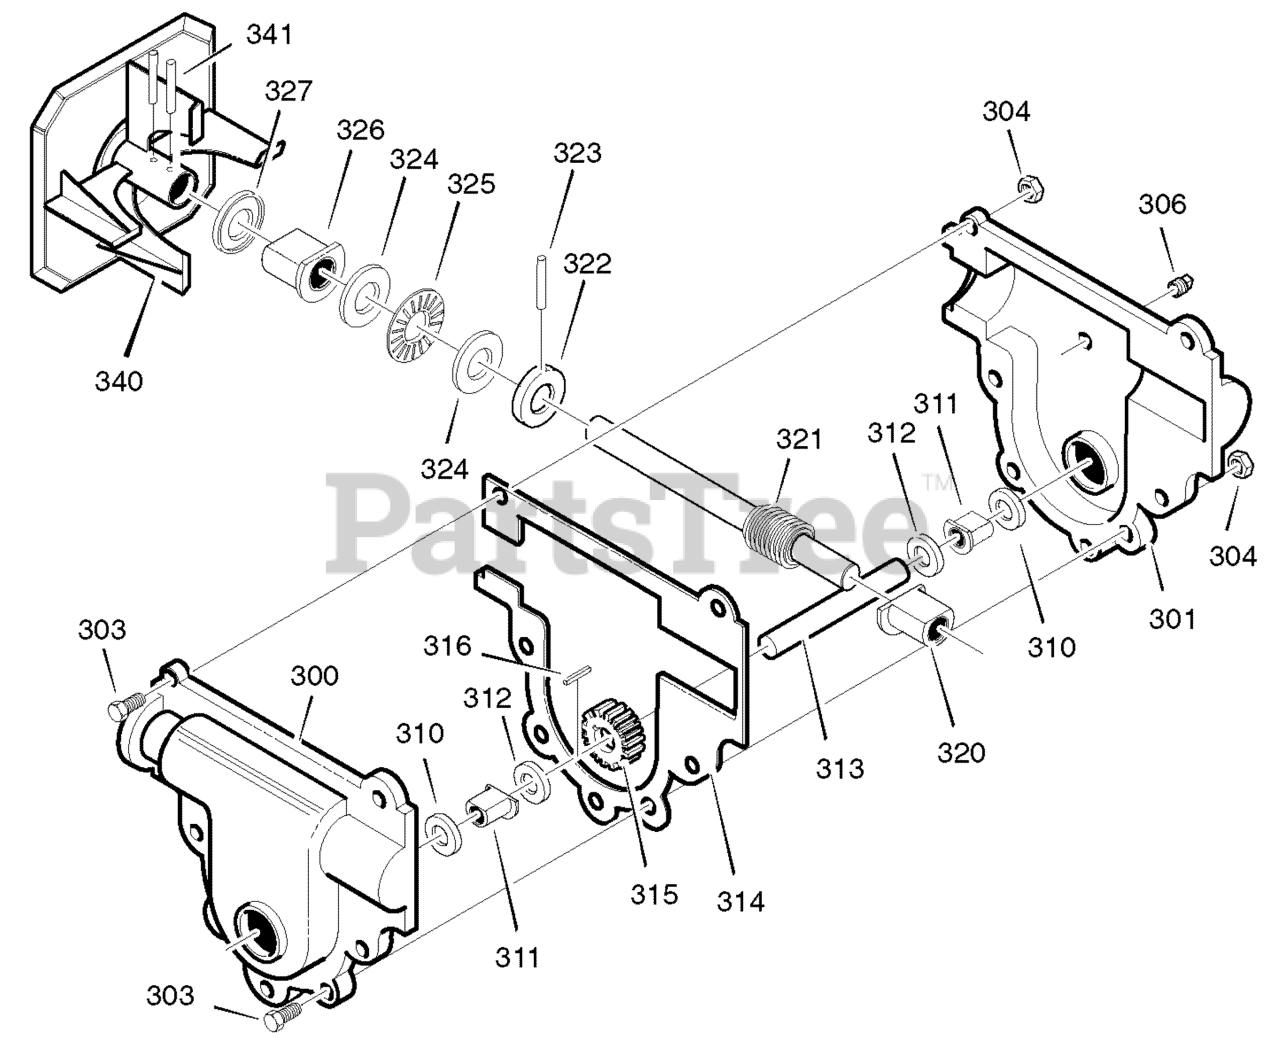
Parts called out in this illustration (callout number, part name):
300	CASE, GEAR, RH
301	CASE, GEAR, LH
303	SCREW,1/4-20X.75
304	NUT,1/4-20
306	SCREW, 3/8-16 x 0.50
310	SEAL, OIL
311	BEARING, FL
312	WASHER, FLAT
313	SHAFT, AUGER OUTPUT
314	GASKET, GEAR BOX
315	GEAR, WORM
316	KEY, WOODRUFF #61
320	BRNG, FL
321	SHAFT, AUGER INPUT (IMPELLER)
322	COLLAR, THRUST
323	PIN, SPRING
324	WASHER, FLAT
325	BRNG, ROLL
326	BRNG, FL
327	SEAL, OIL
341	PIN, SPRING
